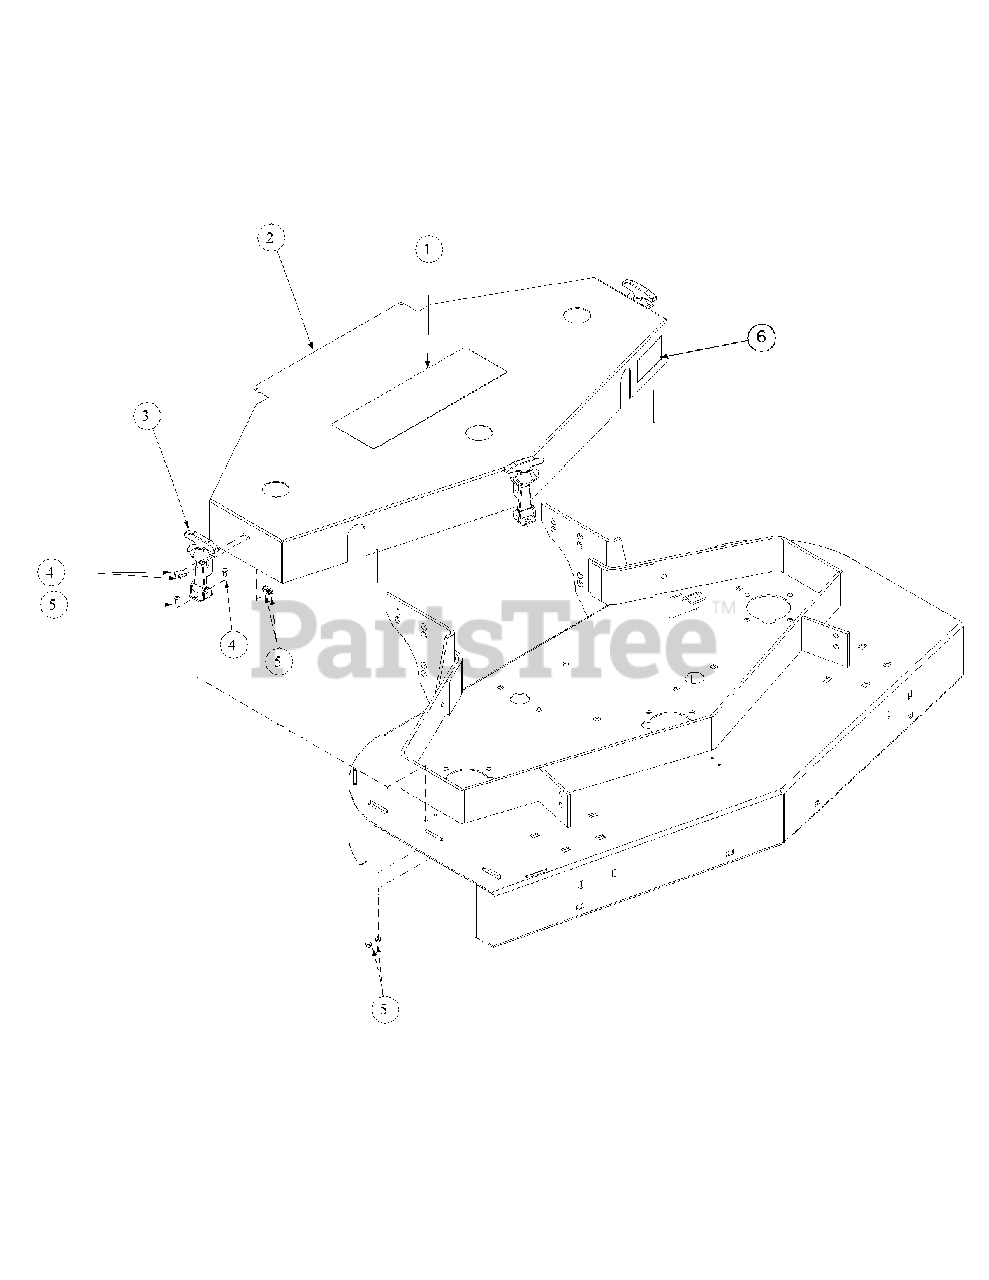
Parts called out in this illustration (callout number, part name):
1	Label Commercial Mower
2	Deck Cover 48"
3	Rubber Latch Hood
4	Machine Screw, 10-24 x 1/2
5	Lock Nut, Nylon Insert, #10-24
6	Label, G1548
